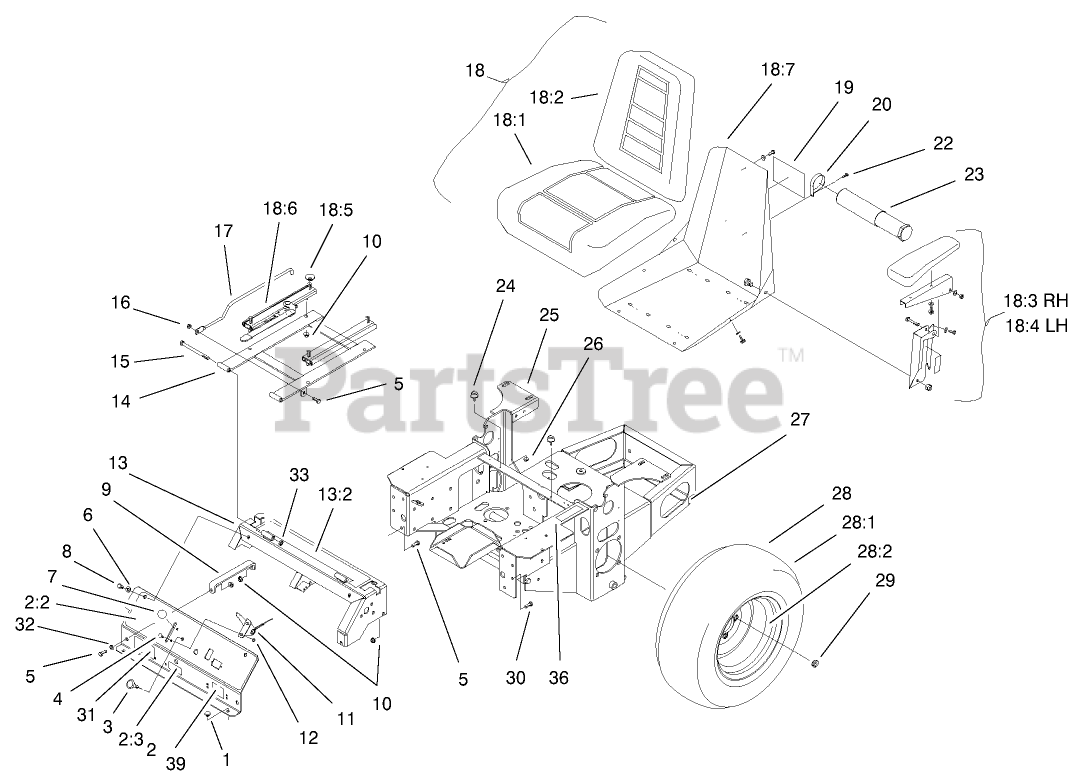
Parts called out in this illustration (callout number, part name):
1	BUMPER
2	INSTRUMENT PANEL ASM
2:2	DECAL,CONSOLE
2:3	DECAL-VALVE, FUEL
3	CONTROL-CHOKE
4	BOLT-CARR
5	SCREW-HH
6	WASHER-PLAIN
7	KNOB-BALL
8	SCREW-HH
9	BRACKET
10	NUT-HF
11	THROTTLE CABLE ASM
12	NUT-LOCK, NI
13	CONSOLE ASM
13:2	DECAL-CONSOLE
14	FRAME-SEAT
15	SCREW-HH
16	NUT-LOCK, NI
17	Rod-Hold Up, Seat
18	SEAT ASM
18:1	CUSHION-SEAT, BOTTOM
18:2	CUSHION-SEAT, BACK
18:3	CUSHION-ARMREST
18:4	CUSHION-ARMREST
18:5	SPACER-TRACK
18:6	TRACK-SEAT
18:7	FRAME-SEAT
19	DECAL
20	CLAMP-R
22	SCREW-HWHTF
23	TUBE-MANUAL
24	BUMPER
25	XREF 103-1944-03
26	NUT-LOCK, NI
27	DECAL-SURFACE, HOT
28	WHEEL AND TIRE ASM
28:1	TIRE
29	NUT-LUG
30	SCREW-HH
31	DECAL-Z149
32	WASHER-FLAT
33	NUT-LOCK, NI
36	DECAL,DRIVE RELEASE
39	DECAL-PROTECTION, EAR
